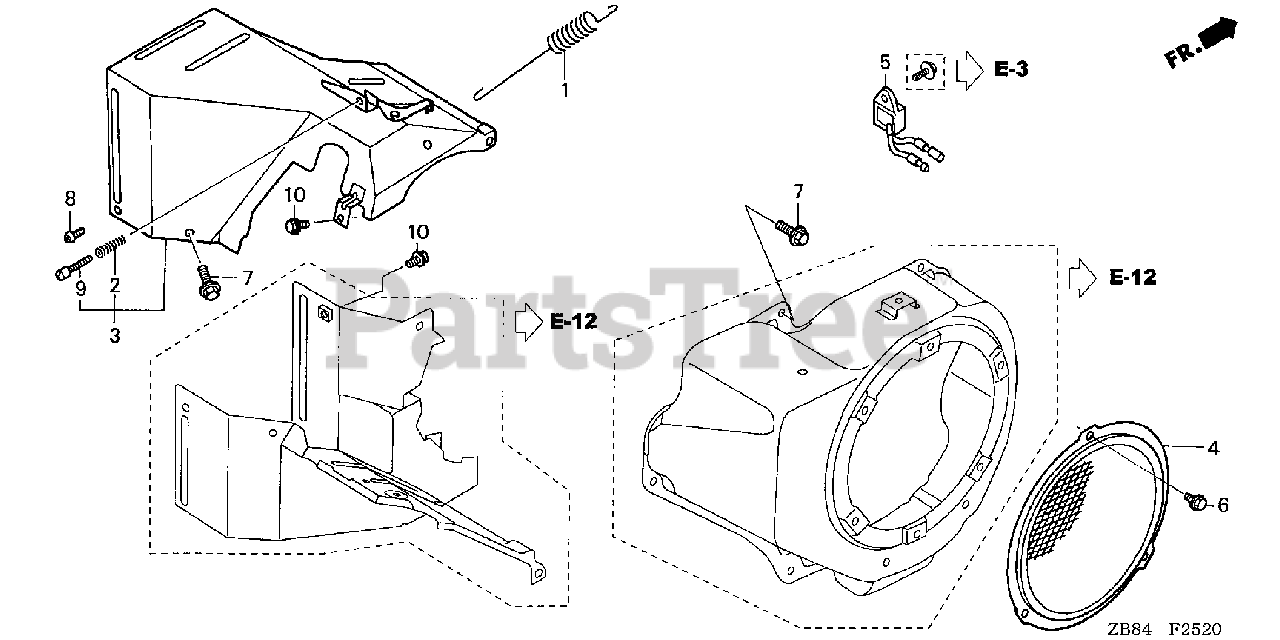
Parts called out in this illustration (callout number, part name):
1	SPRING, GOVERNOR
2	SPRING, CONTROL ADJUSTING
3	SHROUD ASSY. (UPPER)
4	PROTECTOR, FAN COVER
5	ALERT UNIT, OIL
6	BOLT, FLANGE (6X10)
7	BOLT, FLANGE (6X12) (CT200)
8	SCREW, PAN (5X8)
9	SCREW, PAN (5X32)
10	BOLT, FLANGE (6X8)
